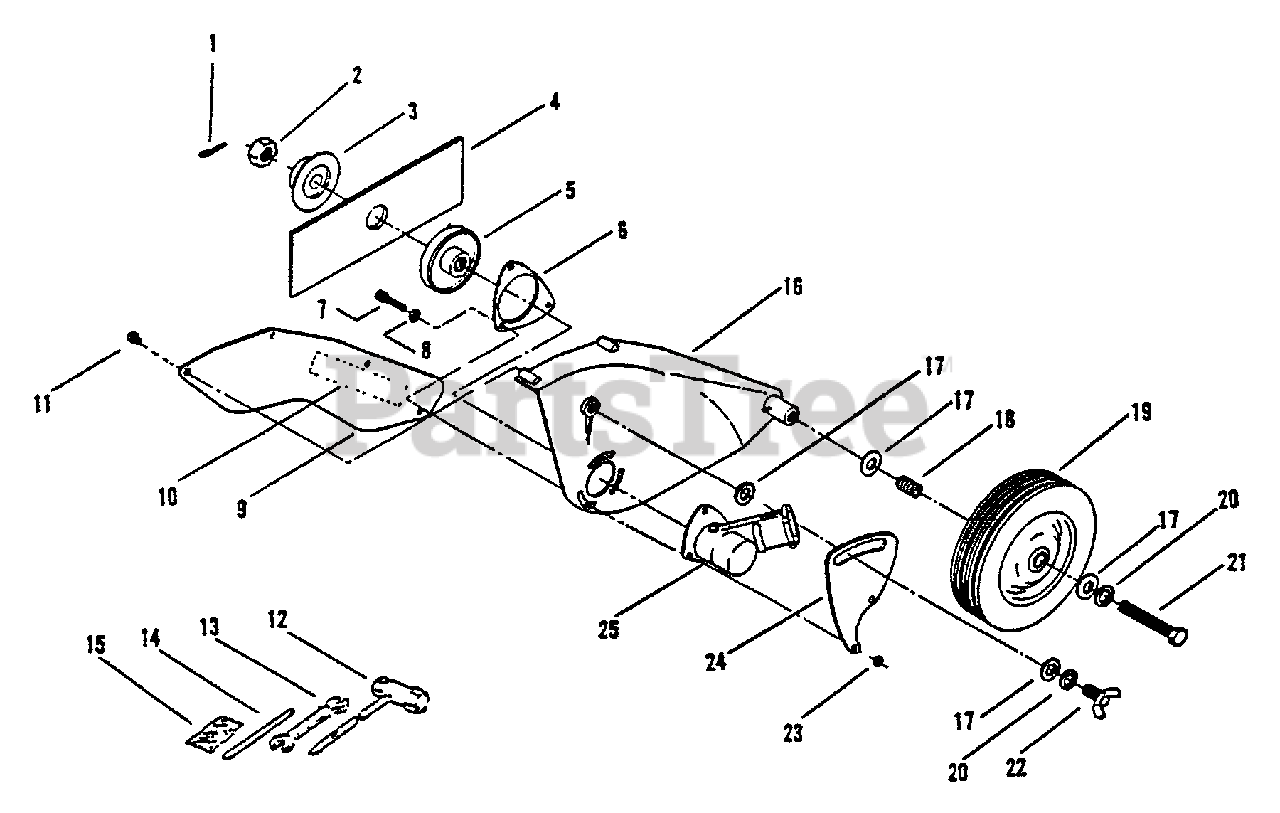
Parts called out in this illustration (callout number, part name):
1	PIN, SPLIT - 2X22
2	NUT - 10 -- LEFT HAND
3	ADAPTOR, BLADE - LOWER
4	BLADE, EDGER
5	ADAPTOR, BLADE - UPPER
6	PLATE, SHIELD
7	SCREW - 5X25
8	WASHER - CONICAL
9	COVER, SHIELD
10	LABEL - CAUTION
11	SCREW - 4X10
12	T-WRENCH - 17X19mm
13	SPANNER - 8X10mm
14	LOCKING TOOL
15	PIN, SPLIT - 2X22
16	SHIELD, DEBRIS
17	WASHER - 8
18	COLLAR - 12
19	WHEEL - 6X1.5
20	WASHER - 5
21	BOLT - 8X60
22	THUMBSCREW
23	LOCKNUT - 5
24	BRACKET, SHIELD
25	GEAR CASE ASSY
